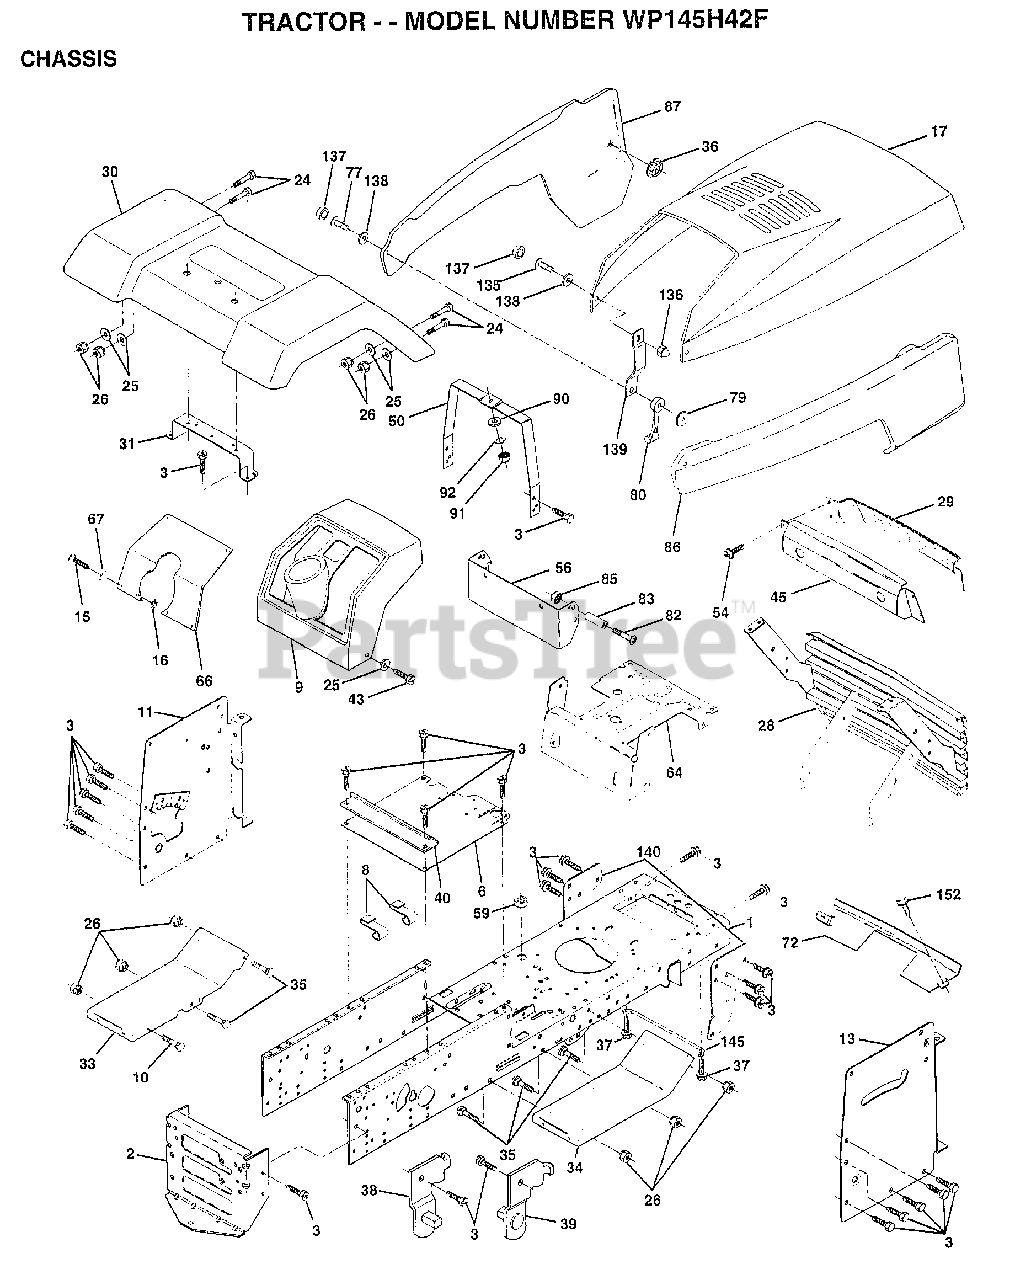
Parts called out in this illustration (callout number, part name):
3	SCREW
6	SADDLE
8	"CLIP,INSULATOR"
9	DASHBOARD BLACK
11	PANEL.DASH.LH.
13	PANEL.DASH.RH.
15	SCREW
24	BOLT
25	WASHER
26	NUT
28	GRILLE ASM PNT
29	PANEL.DASH.RH
30	FENDER.PNT.ASSY
31	BRACKET SUPT FEND
33	FOOTREST.LH.LT/GT
34	FOOTREST.RH.LT/GT
35	BOLT
36	PAL NUT LT
38	BRACKET ASM LH
39	BRACKET ASM RH
40	SPACER FENDER LT
43	SCREW GTV
45	BEZEL.1 PC
50	DASH.SUPT.YP/HUSQ
54	SCREW.HEX.WS.HD
56	EXT DASH LTYT
64	DASH.LOWER.LT
66	"PLATE-DASH,SLSCR"
67	WASHER
72	STRAP.GRILLE.PNT.
77	SCREW
79	WELDNUT
80	HOOD LATCH T
82	SCREW
83	SPACER LT
87	"PANEL SIDE,LH"
90	WASHER PM
92	LOCKWASHER
135	SCREW.10-24X3/8.
136	ACORN NUT RB
137	SNAP CAP LT
138	WASHER LT
139	BKT.SPT.HOOD/PANL
140	BRKT SUSPENSION
145	"ROD POVOT,CHASSIS"
152	SCREW
